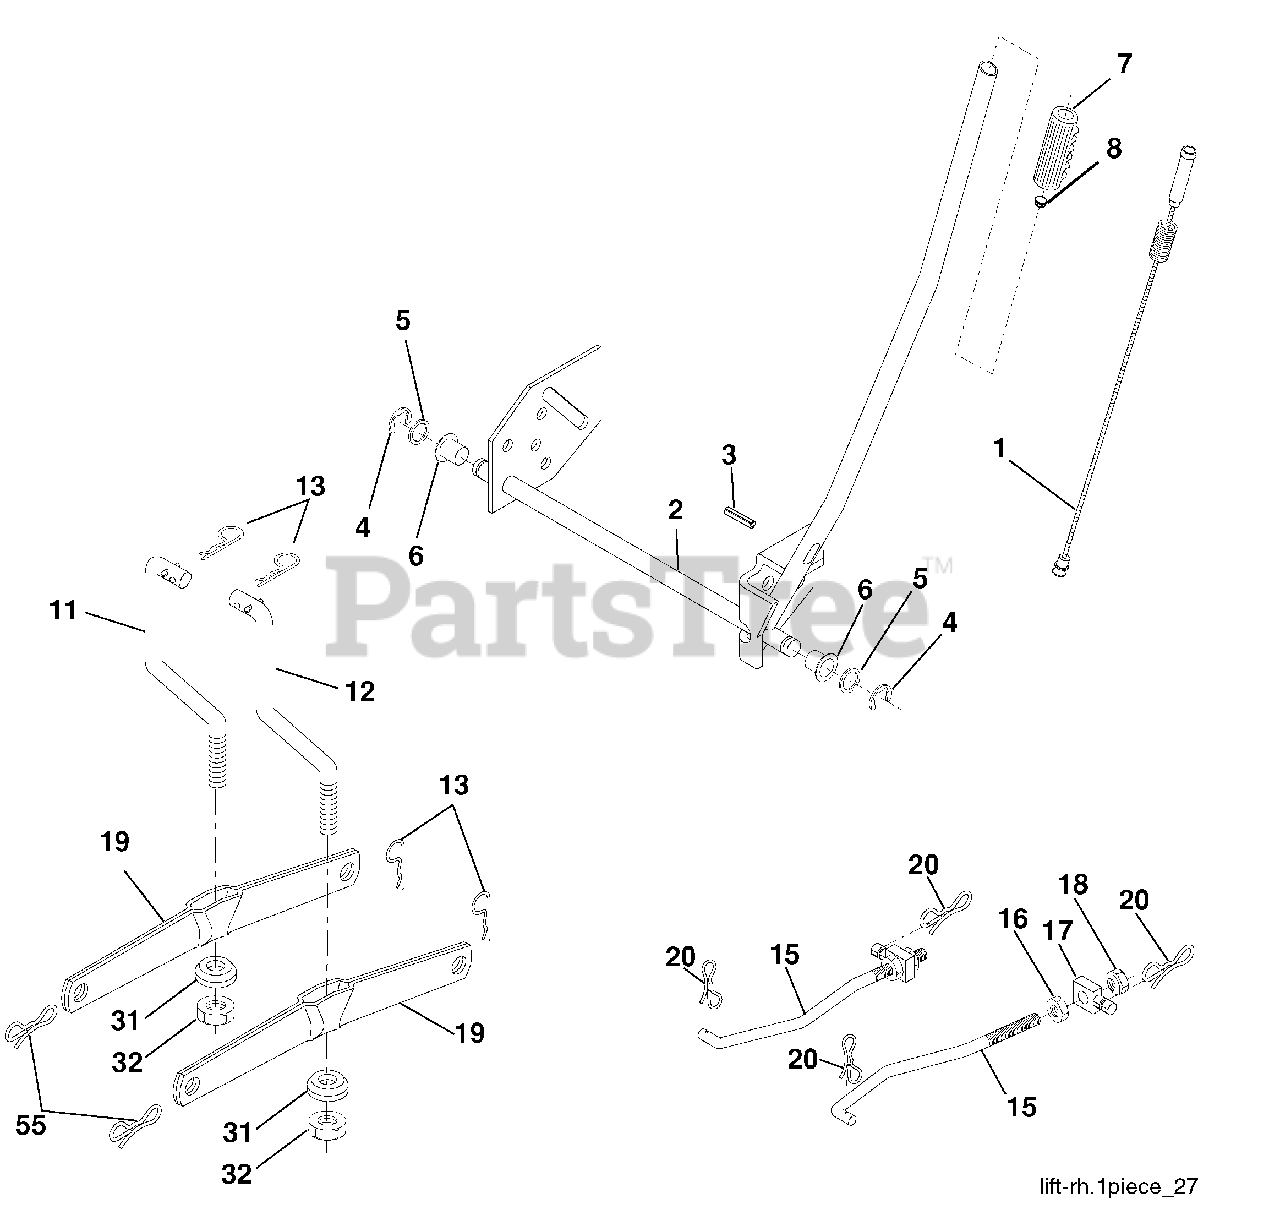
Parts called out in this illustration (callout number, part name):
1	Plunger Asm Lift Lever
2	Shaft Asm Lift RH
3	Pin Groove 1 500 Zinc
4	E Ring #5133-62
5	Washer 21/32 x 1 x 21 Ga.
6	Bearing Nylon Blk 629 Id
7	Grip Handle Bicycle Matte Blk
8	Button Plunger Black
11	Link Lift LH Fixed Length
12	Link Lift RH Fixed Length
13	Retainer Spring
15	Link Front
16	Nut Jam Hex 1/2-13 unc
17	Trunnion
18	Nut Lockw/Wsh 1/2-13 unc
19	Arm Suspension Rear
20	Pin Cotter 7/16 Bow Tie Lock
31	Bearing Pvt Lift
32	Nut Crownlock 3/8-24
55	Pin Cotter 5/16 Bow Tie Lock
